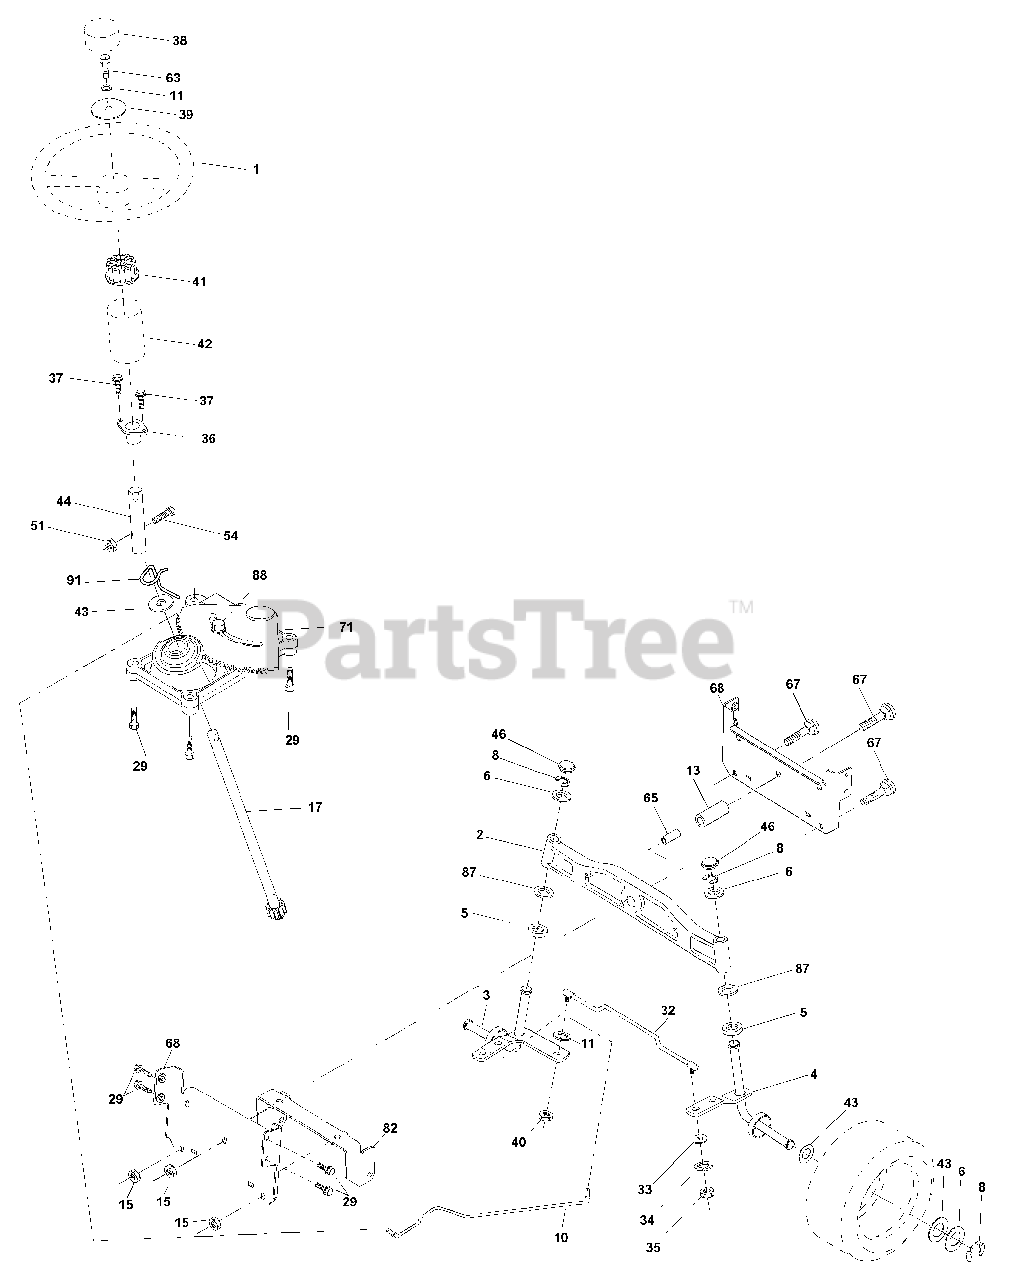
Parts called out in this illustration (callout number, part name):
1	Wheel Steering
2	Axle Cast Lt Machined
3	Spindle Asm LH
4	Spindle Asm RH
5	Bearing Race Thrust Harden
6	Washer 25/32 X 1-5/8 X 16 Ga
8	Ring Klip #t5304-75
11	Washer Lock Hvy Hlcl Spr 3/8
13	Spacer Brg Axle Front
15	Nut Hex Flange Lock
17	Shaft Asm Strg
29	Screw 3/8-16x3/4
32	Rod Tie Ball J
33	Washer 11/32 x 3/4 x 16 Ga.
34	Washer Lock Hvy Helical 5/16
35	Nut Crown Lock 5/16-24Unf
36	Bushing Strg
38	Insert Cap Strg Wh
39	Washer 13/32 x 1-1/20 x 11 Ga
40	Lock nut
41	Adaptor Wheel Strg
42	Boot Steering Shaft
43	Washer 25/32 X 1 1/4 X 16 Ga
44	Extension Steering Shaft LR/LT
46	Cap Spindle Fr Top Blk
51	Nut Lock Hex w/Ins 5/16-18
54	Bolt Fin Hex 5/16-18 Unc x 1-1/4
63	Bolt Fin Hex 3/8-16unc x 1 Gr. 5
65	Spacer Brace Axle
67	Bolt Rdhd Sq 3/8-16 x 2-1/4
68	Axle, Brace
71	Steering Asm
82	Bracket Susp Chassis Front
87	Washer Flat .781 x 1-1/2 x .14
88	Bolt Shoulder 7/16-20
91	Clip Steering
